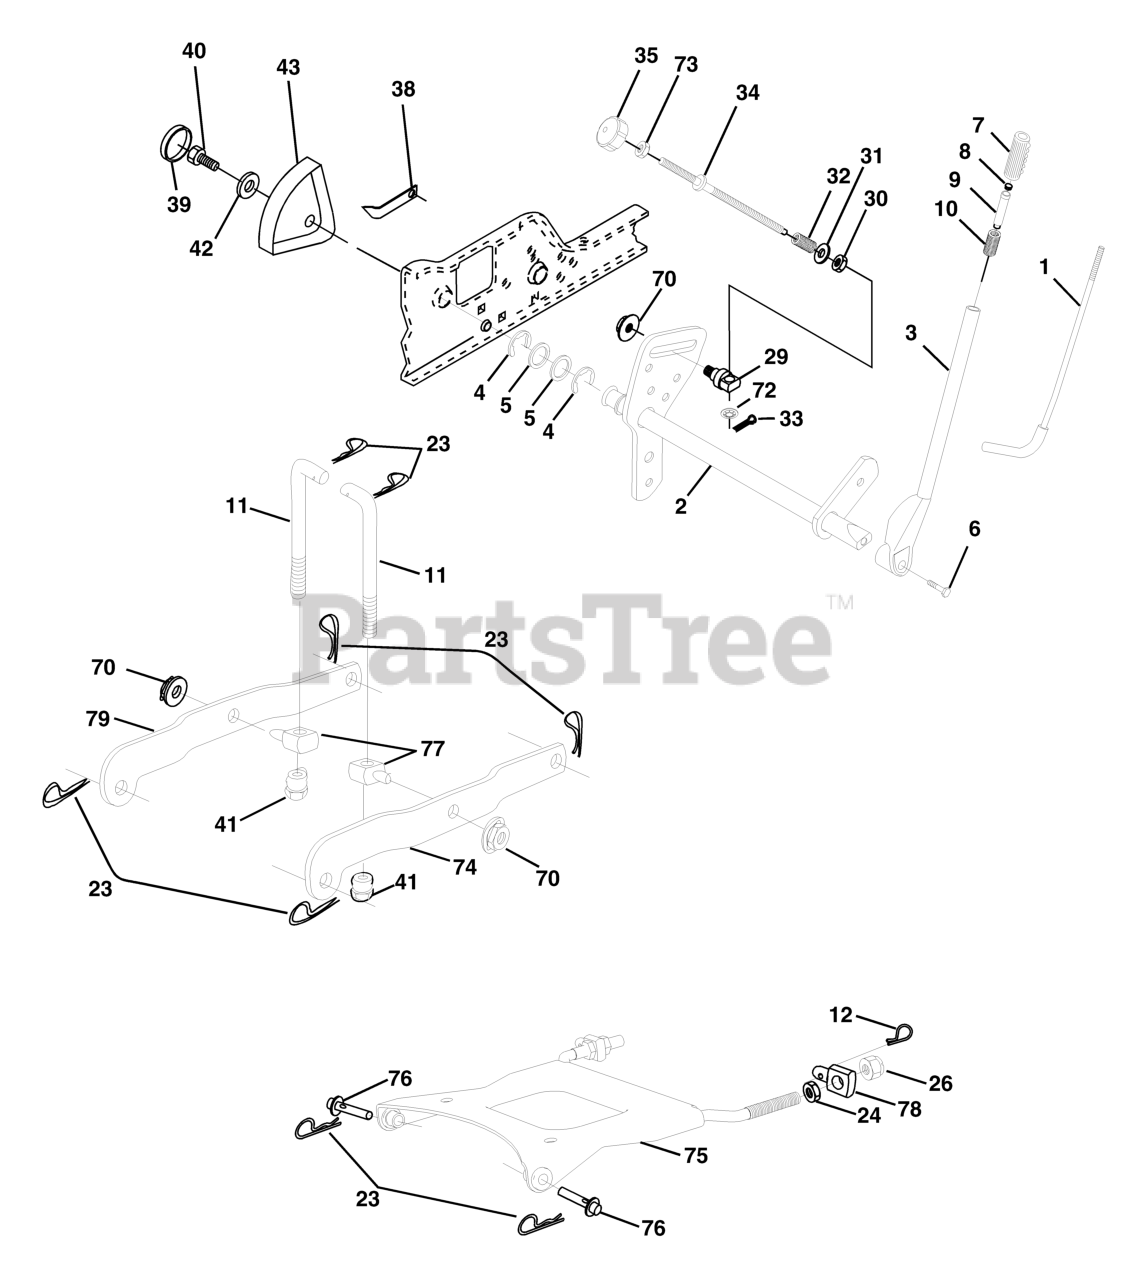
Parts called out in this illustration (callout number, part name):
1	LEVER ROD LT
2	SHAFT ASM., LIFT VGT
3	LEVER ASSY-LIFT RH
5	Washer 29/32 x 1-1/4 x 16 Ga.
6	Bolt, Fin Hex 3/8-16 x 1-1/2
7	GRIP HANDLE
8	PLUNGER BUT KIT
9	PLUNGER BUT KIT
10	SPRING 0.620D X 2.125
11	LIFT LINK
12	SPRING RETAINER
23	RETAINER-SPRNG RB
24	NUT.HEX.JAM.1/2-13
26	NUT LTV
32	SPRING.COMP.INF.H
33	COTTER PIN
34	ROD.LIFT.ADJUSTABLE
35	KNOB INF 3/8-16
38	POINTER, HEIGHT INDICATOR(2 2)
40	SCREW 5/16-18X1
41	NUT, LIFT LINK 7/16-20
43	HEIGHT INDICATOR
70	NUT
72	NUT PUSH M
73	NUT
74	ARM SUSP REAR RH
75	PLATE ASM SUSP FRONT
76	PIN.FLANGE
79	ARM SUSP. REAR LH
